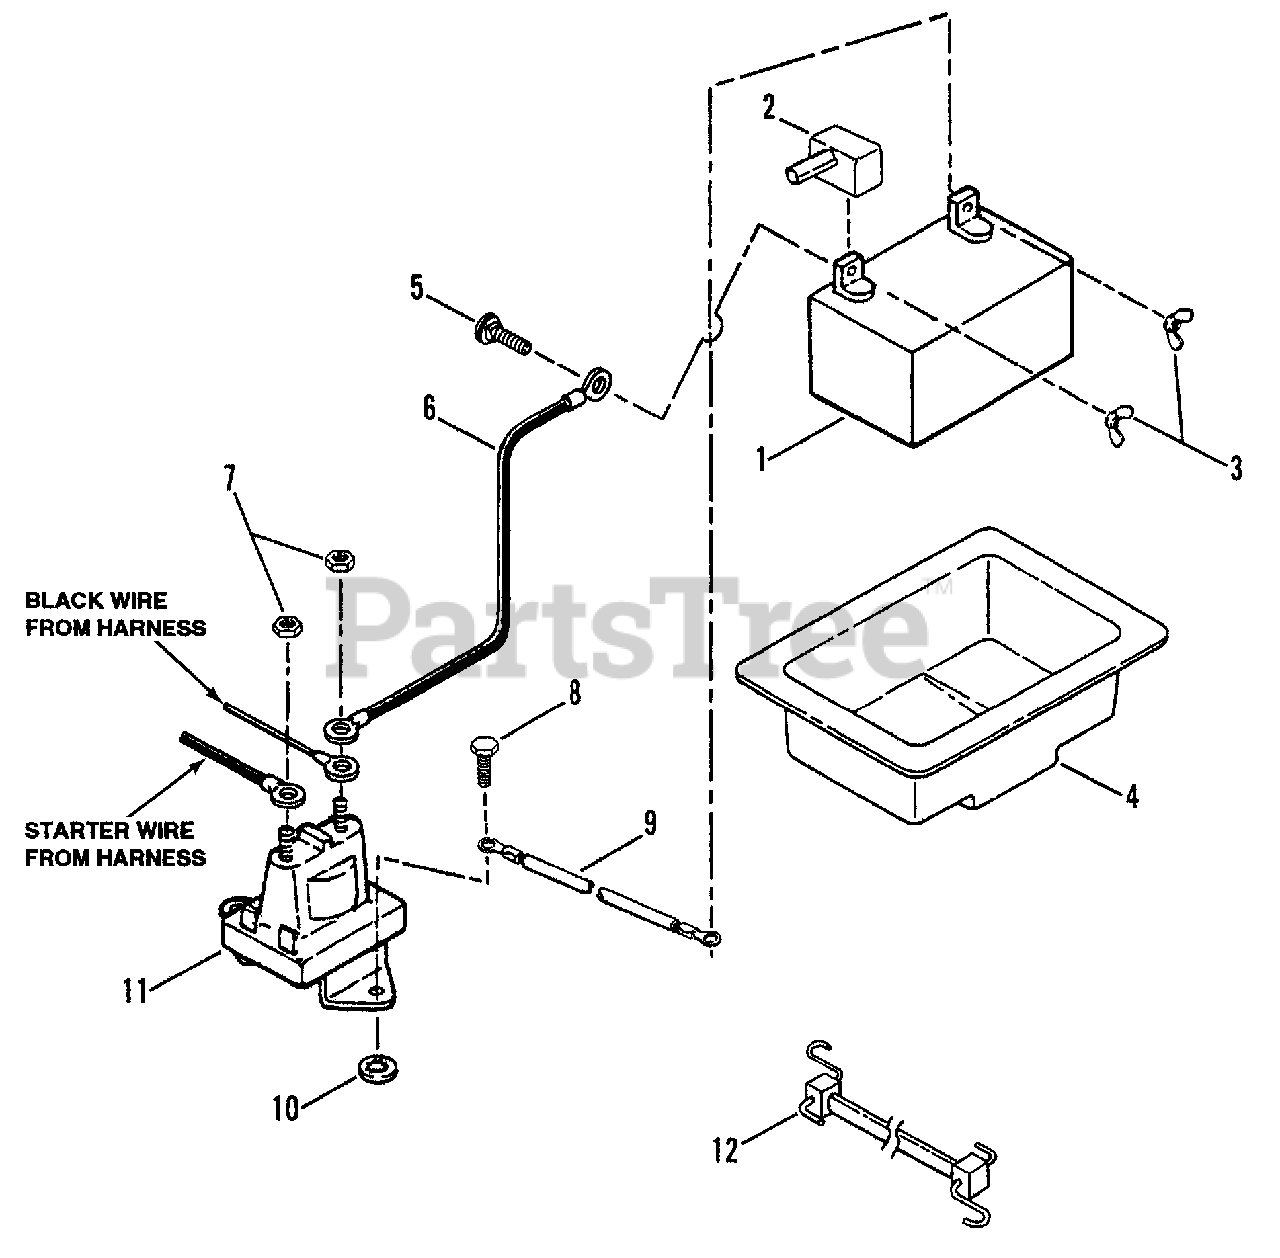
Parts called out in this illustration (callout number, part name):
1	KIT, Battery
2	COVER, Positive Terminal
3	WING-NUT, 1/4-20
4	TRAY, Battery
5	BOLT, 1/4-20 x 3/4" Carriage
6	CABLE, Positive (Red)
7	NUT, 1/4-20 Hex Jam
8	SCREW, 1/4-20 x 1/2" Self-Tapping
9	CABLE, Ground (Black)
10	RETAINER, 1/4 Bolt
11	SOLENOID
12	TIE, Strap
